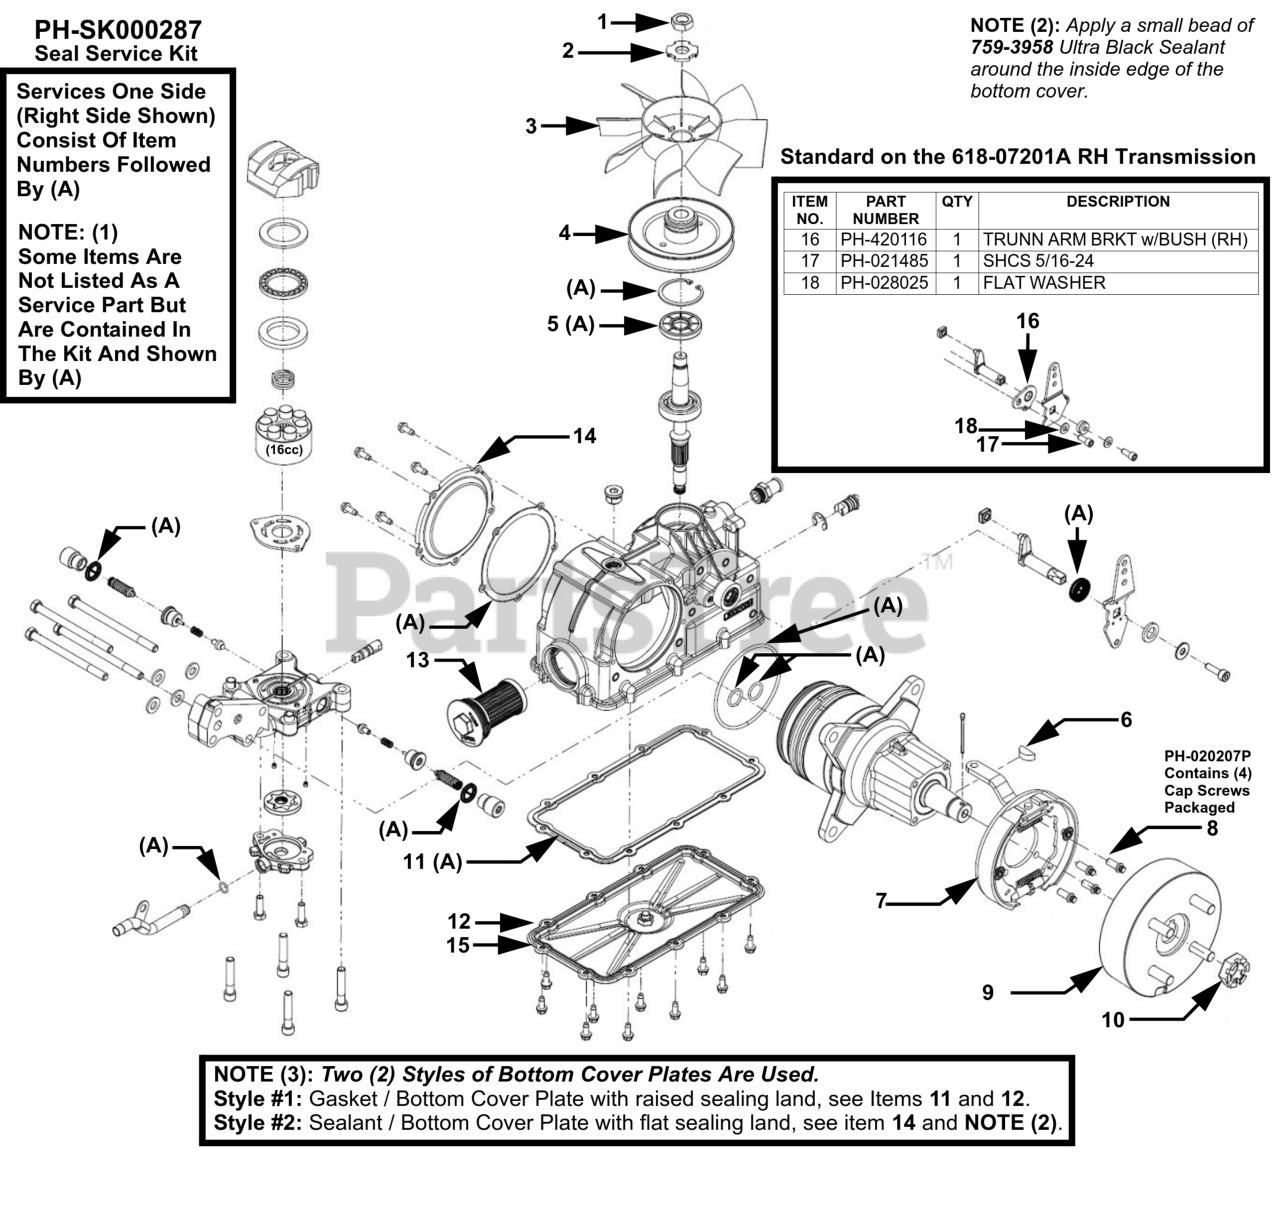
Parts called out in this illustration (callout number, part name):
6	WOODRUFF KEY
7	BRAKE ASSEMBLY-ON HOLE LEVER
8	SCREW-CAP (QTY 4)
9	DRUM-4 BOLT BRAKE
10	NUT-SLOTTED
11	BOTTOM COVER GASKET
12	BOTTOM COVER
14	SIDE COVER PLATE
15	BOTTOM COVER
16	TRUNNION ARM BRACKET (RH)
17	CAP SCREW 5/16-24
18	FLAT WASHER
19	BRACKET-ROTATING
A	SEAL SERVICE KIT
